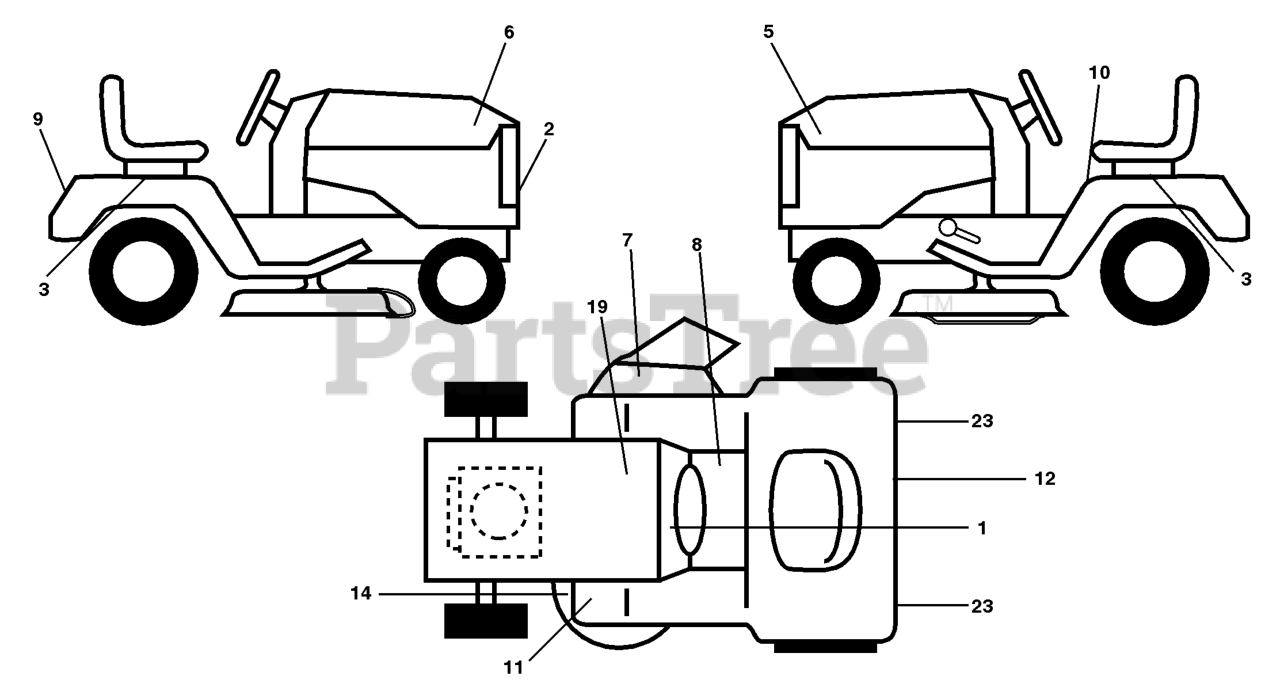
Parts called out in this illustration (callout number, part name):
1	DECAL, OPERATING INSTRUCTIONS
2	DECAL.GRILLE.HUSQ
3	DECAL, FENDER
5	DECAL, HOOD LH GTH220 HYDRO
6	DECAL HOOD RH GTH220 HYDRO
7	DECAL WARNING (ENGLISH/FRENCH)
8	DECAL PARK BRAKE
9	DECAL FENDER HUSQ
10	DECAL FENDER DANGER
12	DECAL D-BAR
14	DECAL V-BELT SCHEMATIC
19	DECAL BTRY SYMBOLS
23	REFLECTOR-TAIL YT
